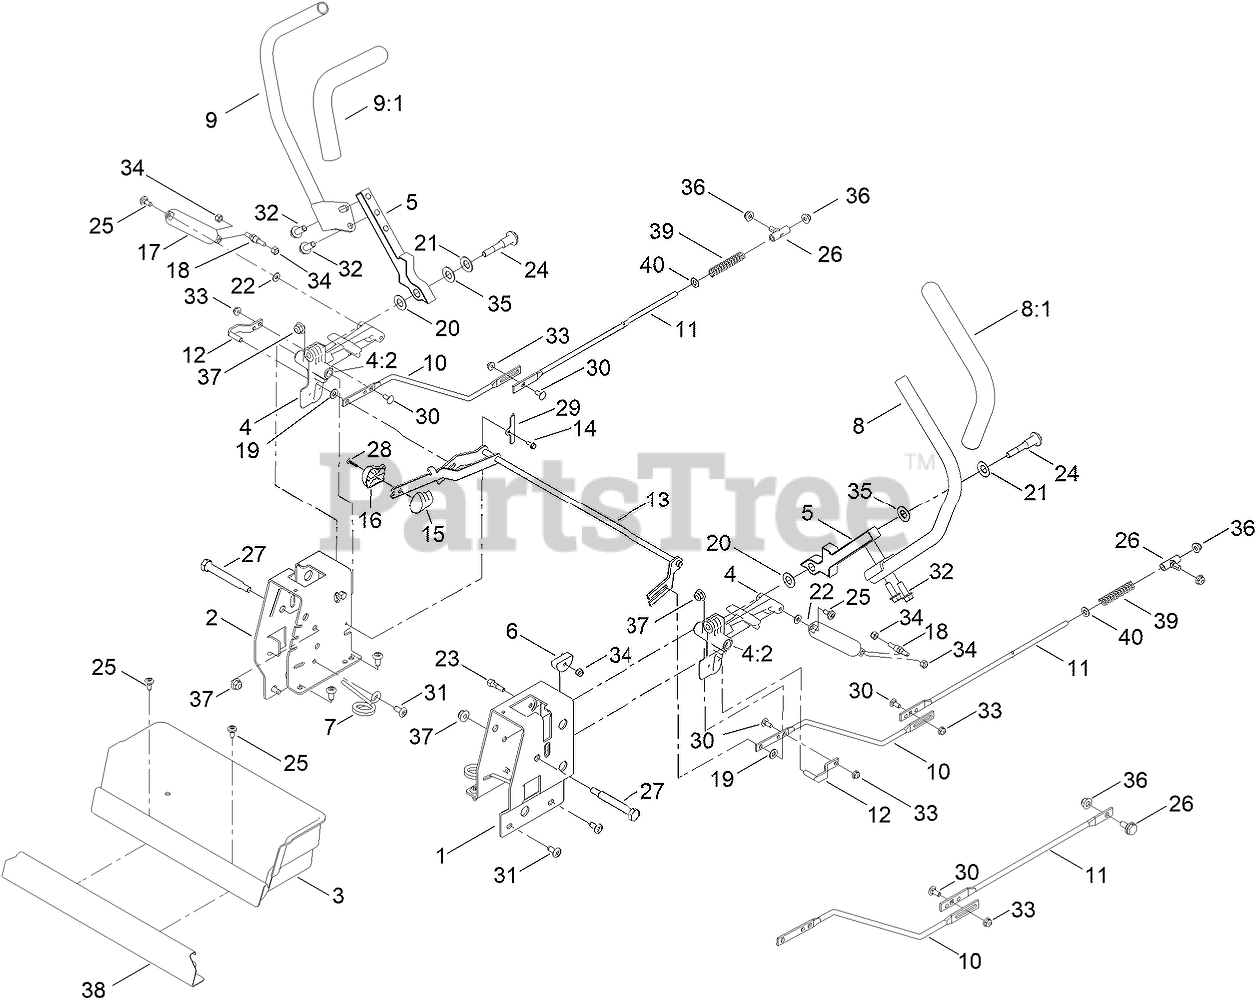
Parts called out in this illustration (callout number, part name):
1	PLATE-CONTROL BOX, LH
2	PLATE-CONTROL BOX, RH
3	BOX-STORAGE
4	ACTUATOR ARM ASM
4:2	BUSHING-FLANGE
5	ARM-CONTROL
6	ECCENTRIC
7	SPRING-TORSION
8	HANDLE-CONTROL, LH
9	HANDLE-CONTROL, RH
10	ROD-HYDRO, FRONT
11	ROD-HYDRO, REAR
12	PIN-ROD, HYDRO
13	SPEED CONTROL ASM
14	PLATE-RETAINER
15	KNOB-RH
16	KNOB-LH
17	DAMPER-NON CAVITATING
18	STUD-DAMPER
19	SPACER-NYLON
20	WASHER-NYLON
21	WASHER-BELLEVILLE
22	WASHER
23	BOLT-PIVOT, ECCENTRIC
24	BOLT-PIVOT
25	SCREW-SHOULDER
26	MOUNT-ROD, HYDRO
27	BOLT-PIVOT
28	SCREW-PPH
29	SCREW-TAPTITE
30	SCREW-CARR
32	SCREW-HHF
33	NUT-HF
34	NUT-LOCK, NI
35	WASHER
36	NUT-HF
37	NUT-HF, NI
38	PLATE-KICK
39	SPRING-COMPRESSION
40	WASHER-PLAIN
